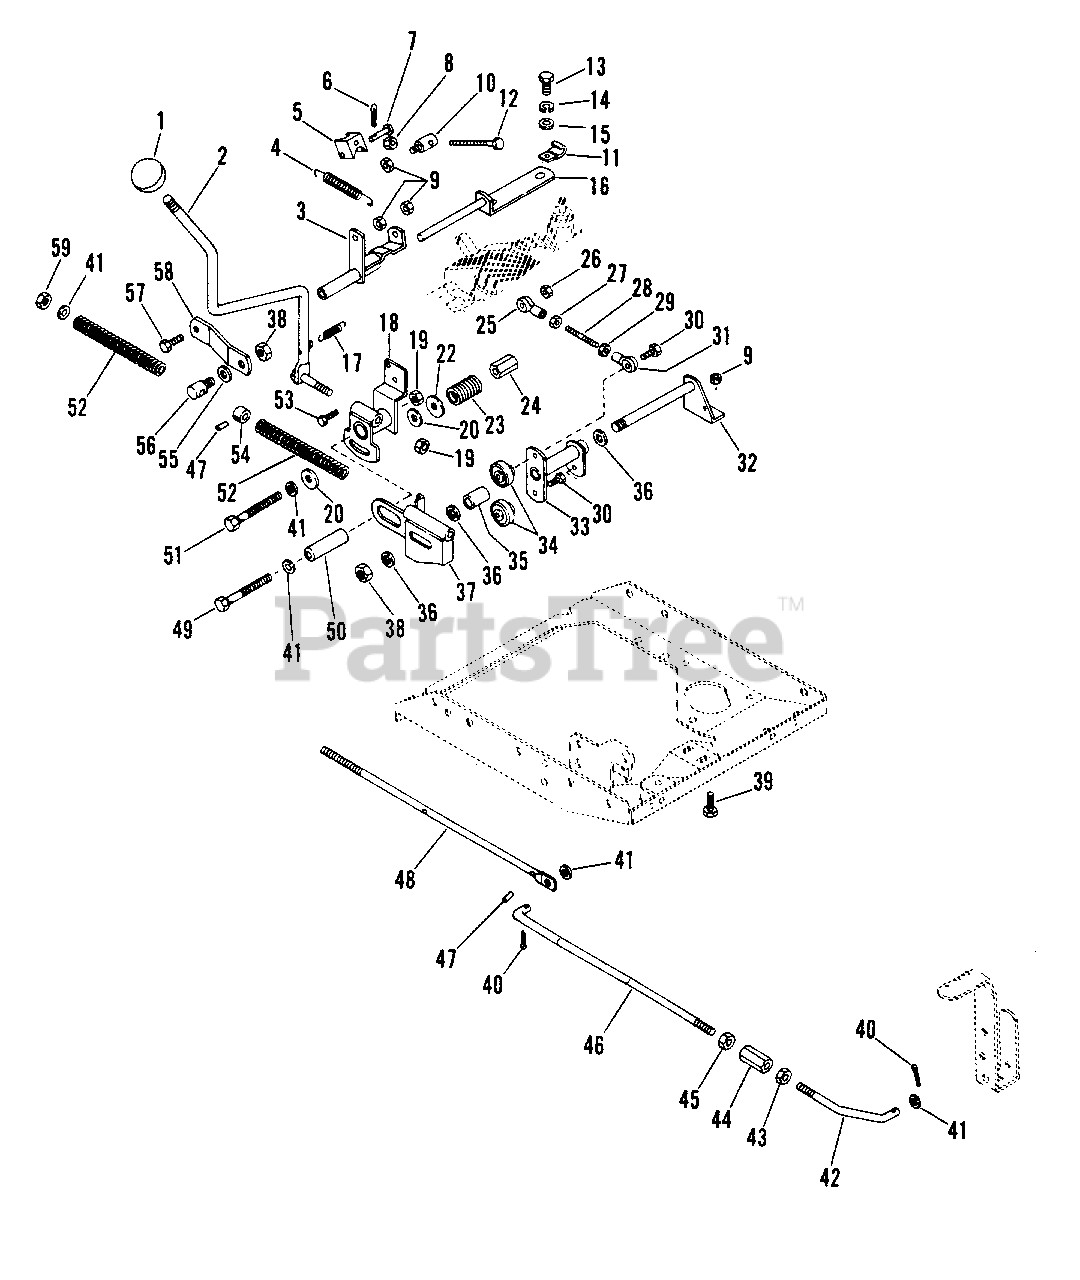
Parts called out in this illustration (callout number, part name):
1	BALL
2	HANDLE, SHIFT
3	TUBE, BRAKE
4	SPRING, EXTENSION
5	CLEVIS
6	PIN, CLEVIS .094X.75
7	PIN, CLEVIS
8	NUT, HEX 5/16-18
9	NUT, LOCK 5/16-18
10	PIVOT, ROD
11	J-CLAMP
12	BOLT, HEX 5/16-18X3.50
13	BOLT, HEX 5/16-18X.625
14	WASHER, LOCK 5/16 EXT. TH. TYA
15	WASHER, FLAT .312X.734X.065
16	BRACKET, BRAKE
17	SPRING, EXTENSION
18	SHIFT, BRACKET
19	NUT, LOCK 3/8-16
20	WASHER, FRICTION
22	WASHER, .411X1.25X.125
23	SPRING, COMPRESSION
24	NUT, GUIDE 3/8-16
25	ROD END, L.H.
26	NUT, LOCK 1/4-20
27	NUT, HEX 1/4-28 L.H.
28	STUD
29	NUT, HEX 1/4-28
30	BOLT, HEX 1/4-28X.75
31	ROD END, R.H.
32	PIVOT, BRAKE
33	CONTROL, SHIFT
34	BEARING, BALL
35	SPACER
36	WASHR, FLAT .531X.062X.095
37	BRACKET, BRAKE
38	NUT, LOCK 1/2-13
39	BOLT, 5/16-18X.625 RD HD SQ NK
40	PIN, COTTER .125X.75
41	WASHER, FLAT .406X.812X.065
42	ROD, FRONT BRAKE
43	NUT, HEX 3/8-16
44	NUT, COUPLING
45	NUT, HEX 3/8-16 L.H.
46	ROD, REAR BRAKE
47	PIN, GROOVE .125X.625
48	ROD, BRAKE
49	CAP-SCREW, HEX 3/8-16X3.25
50	SPACER
51	BOLT, HEX 3/8-16X3.25
52	SPRING, COMPRESSION
53	BOLT, HEX 1/4-20X.875
54	BUSHING, LOCATOR
55	WASHER, FLAT .52X.81X.033
56	ADAPTER, UNIVERSAL ROD
57	BOLT, HEX 5/16-18X1.00
58	LINK, BRAKE
59	NUT, LOCK 3/8-24
